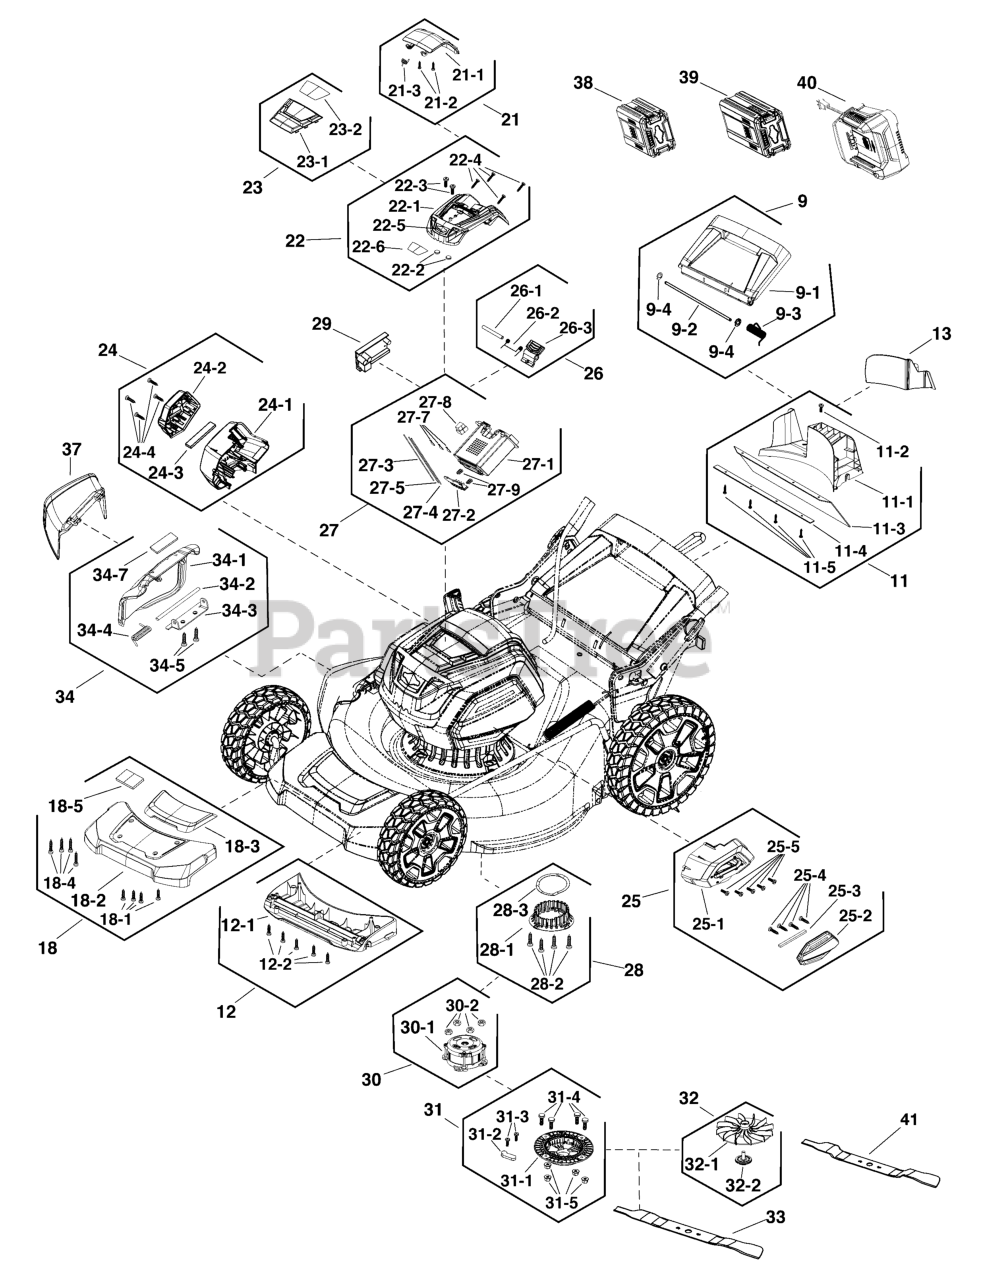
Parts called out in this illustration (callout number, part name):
9	KIT, Rear Cover
9-1	COVER, Rear
9-2	PIN
9-3	SPRING
9-4	WASHER, Split
11	KIT, REAR BAFFLE
11-1	REAR BAFFLE
11-3	COVER
11-4	PLATE
12	KIT, Front Bulkhead
12-1	BAFFLE, Front
13	MULCH PLUG
18	KIT, Front Panel
18-2	BUMPER
18-3	COVER, Bumper
18-5	DECAL
21	KIT, Battery Cover
21-1	COVER, Battery
21-3	SPRING
22	KIT, Top Cover
22-1	COVER, Top
22-2	MAGNET
22-5	B&S LOGO
22-6	LABEL
23	KIT, Cover
23-1	TOP COVER
23-2	SHROUD
24	KIT, RIGHT COVER
24-1	COVER, Right
24-2	COVER, Right
24-3	SCREEN, Dust
25	KIT, Left Cover
25-1	COVER, Left
25-2	HOUSING, Left
25-3	SCREEN, Dust
26	KIT, RELEASE BUTTON
26-1	PIN
26-2	SPRING
26-3	BUTTON
27	KIT, BATTERY COMPARTMENT
27-1	HOUSING, Battery
27-2	TERMINAL
27-3	WIRE, Red
27-4	WIRE, Yellow
27-5	WIRE, Black
27-7	CONTACT
27-8	CONNECTOR
27-9	SPRING
28	KIT, BASE
28-1	BASE
28-3	SEAL
29	KIT, PCB, NA
30	KIT, Motor
30-1	MOTOR
30-2	NUT
31	KIT, MOTOR BASE
31-1	MOTOR BASE
31-2	DISC, Tension
31-4	BOLT
31-5	NUT
32	KIT, Fan
32-1	FAN
32-2	KIT, Bolt
33	KIT, Blade
34	KIT, COVER, NA
34-1	SIDE DISCHARGE COVER
34-2	PIN
34-3	BRACKET
34-4	SPRING, Torsion
34-5	BOLT
34-7	LABEL
37	KIT, Deflector
38	* BATTERY, 2.0, 82V NA
39	* BATTERY, 4.0, 82V NA
40	* CHARGER, Battery, NA
41	BLADE, Mulching, 19"
